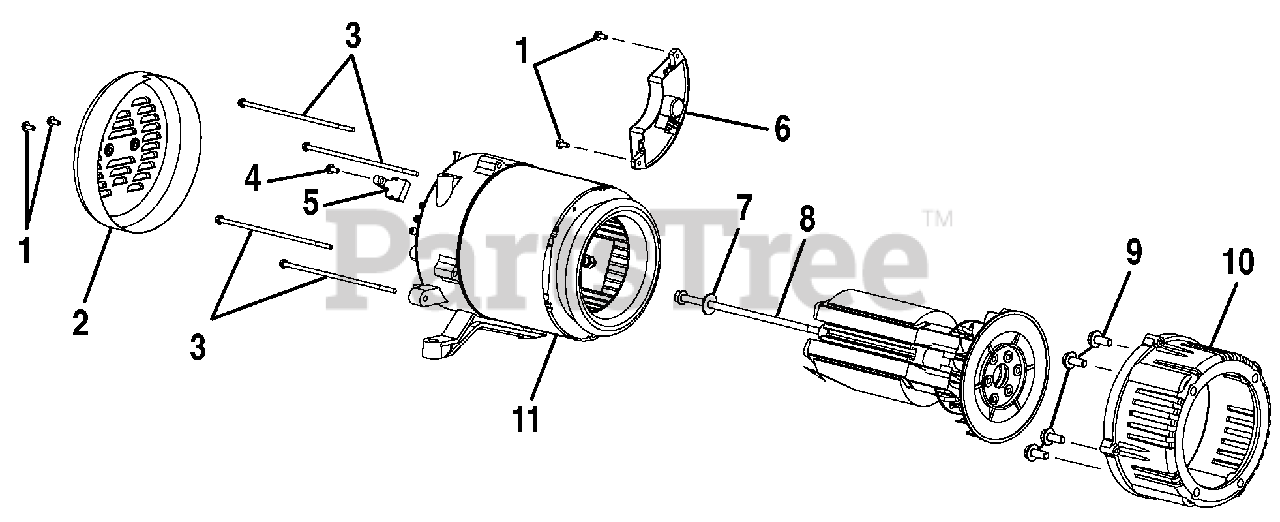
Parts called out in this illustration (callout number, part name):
1	Bolt (M5 x 14 mm)
2	Brush Cover
3	Bolt (M6 x 175 mm)
4	Bolt (M5 x 18 mm, Brush Assembly)
5	Brush Assembly
6	Automatic Voltage Regulator
7	Washer (M5)
8	Bolt (M10 x 270 mm)
9	Bolt (3/8-18 x 1-1/4 in.)
10	Engine Adapter
11	Stator Cover
